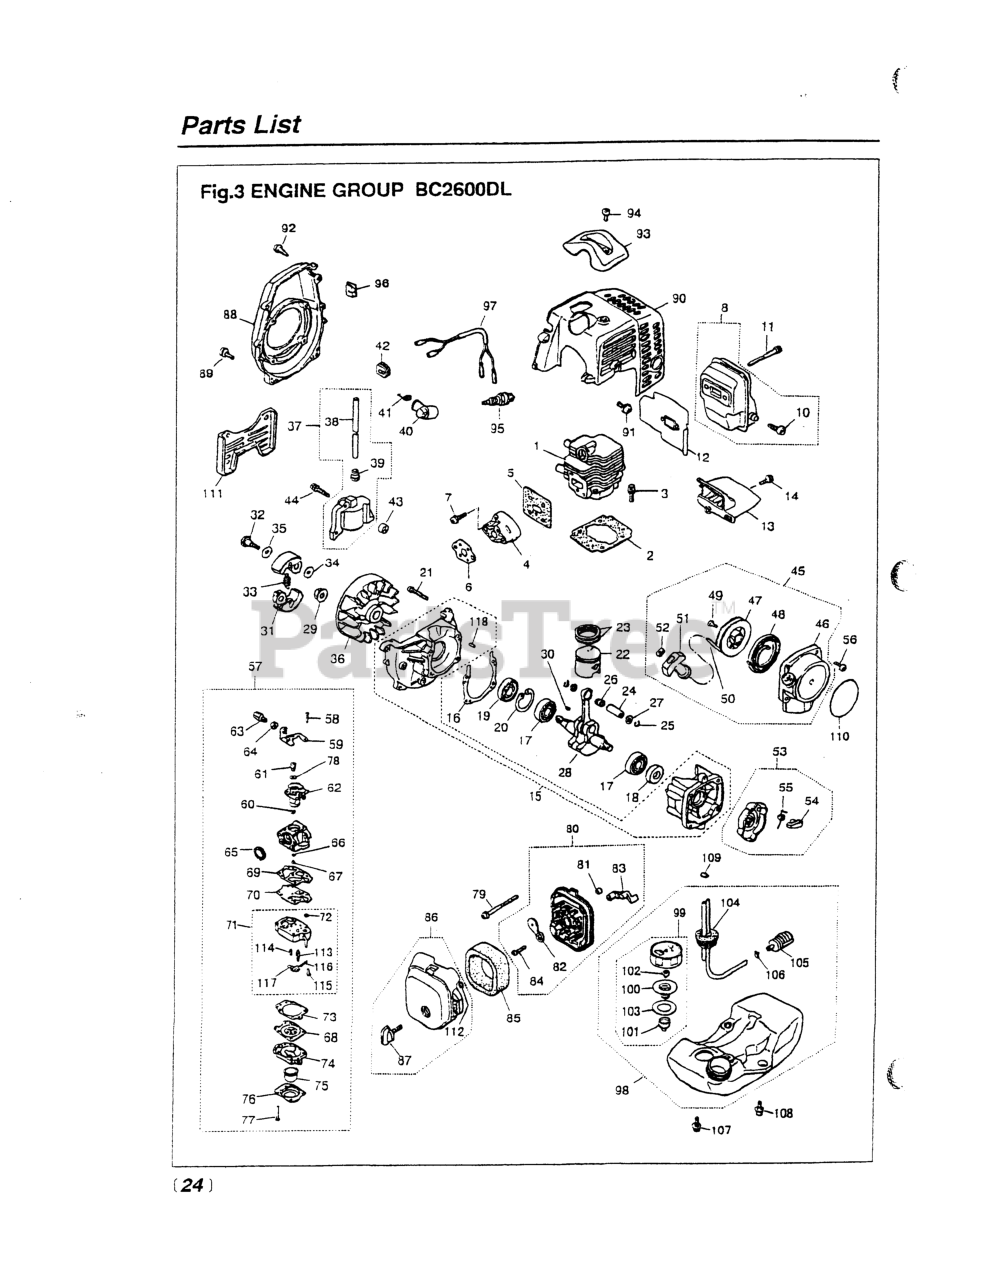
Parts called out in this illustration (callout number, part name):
1	CYLINDER
3	BOLT, M5 X 22
4	INSULATOR (USE -13163)
5	GASKET (RPLS -13120)
6	GASKET (REPLACES -13130)
7	SCREW, M5X20 (RPLS.1400-75510)
8	MUFFLER ASSY (RPLS 5501- )
10	ARRESTER (RPLS 5850-15140)
11	BOLT, M5 x 50
12	GASKET, MUFFLER (RPLS -15111)
14	SCREW, M4 X 16
15	CRANKCASE
16	GASKET (RPLS -21140)
17	BEARING
18	SEAL, OIL (RPLS 1100-21210)
19	SEAL, OIL (RPLS 1140-21220)
20	RING, SNAP, M28 x 1.2
21	BOLT, M5 X 30
22	PISTON
23	RING, PISTON
24	PIN, PISTON
25	RING, SNAP (RPLS 1101-41320)
27	WASHER
28	CRANKSHAFT (RPLS 1850-42000)
30	KEY
31	SHOE (RPLS 1100-51114)
32	BOLT
33	SPRING, CLUTCH (RPLS-51220)
34	WASHER, FLAT (USE 182303)
36	ROTOR
37	COIL ASSY (RPLS 5500-71200)
38	CORD
39	CAP
41	SPRING
42	GROMMET
43	SPACER (RPLS -71260)
44	BOLT
45	RECOIL ASSEMBLY
46	CASE
47	REEL
48	SPRING, SPIRAL
49	SCREW (RPLS -75150)
51	KNOB
52	PLATE, STOPPER
53	PULLEY ASSY (RPLS -75210)
54	RATCHET (RPLS 1850-75220)
55	SPRING, RETURN
56	SCREW, M4 X 16
57	CARBURETOR (WYJ-117)
58	SCREW
60	RING
61	SWIVEL
62	VALVE ASSY
63	SCREW, CABLE ADJUSTER
64	NUT, CABLE ADJUSTER
65	RING, PACKING
66	RING, O
67	JET
68	DIAPHRAGM (USE 4810-81260)
69	GASKET, PUMP
70	DIAPHRAGM
71	BODY, PUMP
73	GASKET, DIAPHRAGM
74	BODY, PURGE
75	PUMP, PRIMING
76	COVER, PUMP
77	SCREW
78	WASHER
79	SCREW, M5 X 55
80	BODY-A (RPLS -82101)
81	SLEEVE
82	PLATE, CHOKE (RPLS-82130)
83	LEVER, CHOKE
84	SCREW (REPLACES 50030272)
85	ELEMENT
87	KNOB (RPLS -82220)
88	COVER, FAN (RPLS-31110)
89	SCREW, M5X20 (RPLS.1400-75510)
90	COVER, ENGINE (RPLS -32111)
91	SCREW, M5 x 12
92	SCREW, HOUSING
93	GUARD, PLUG
94	SCREW,M5 X 14 (RPLS 1400-15510
97	CORD COMP (RPLS -73200)
101	HOLDER, CAP
102	VALVE (NLA WHEN OUT)
103	PACKING
104	PIPE COMPLETE
105	FILTER (RPLS 1850-85300)
106	CLIP (REPLACES 2841-31280)
107	SCREW
108	SCREW W/ WASHER
109	CLIP
110	LABEL, RECOIL (RPLS -91120)
111	STAND
112	RING
113	VALVE, INLET
114	SPRING, METERING LEVER
115	SCREW, METERING LEVER PIN
116	PIN, METERING LEVER
117	LEVER
118	PIN
